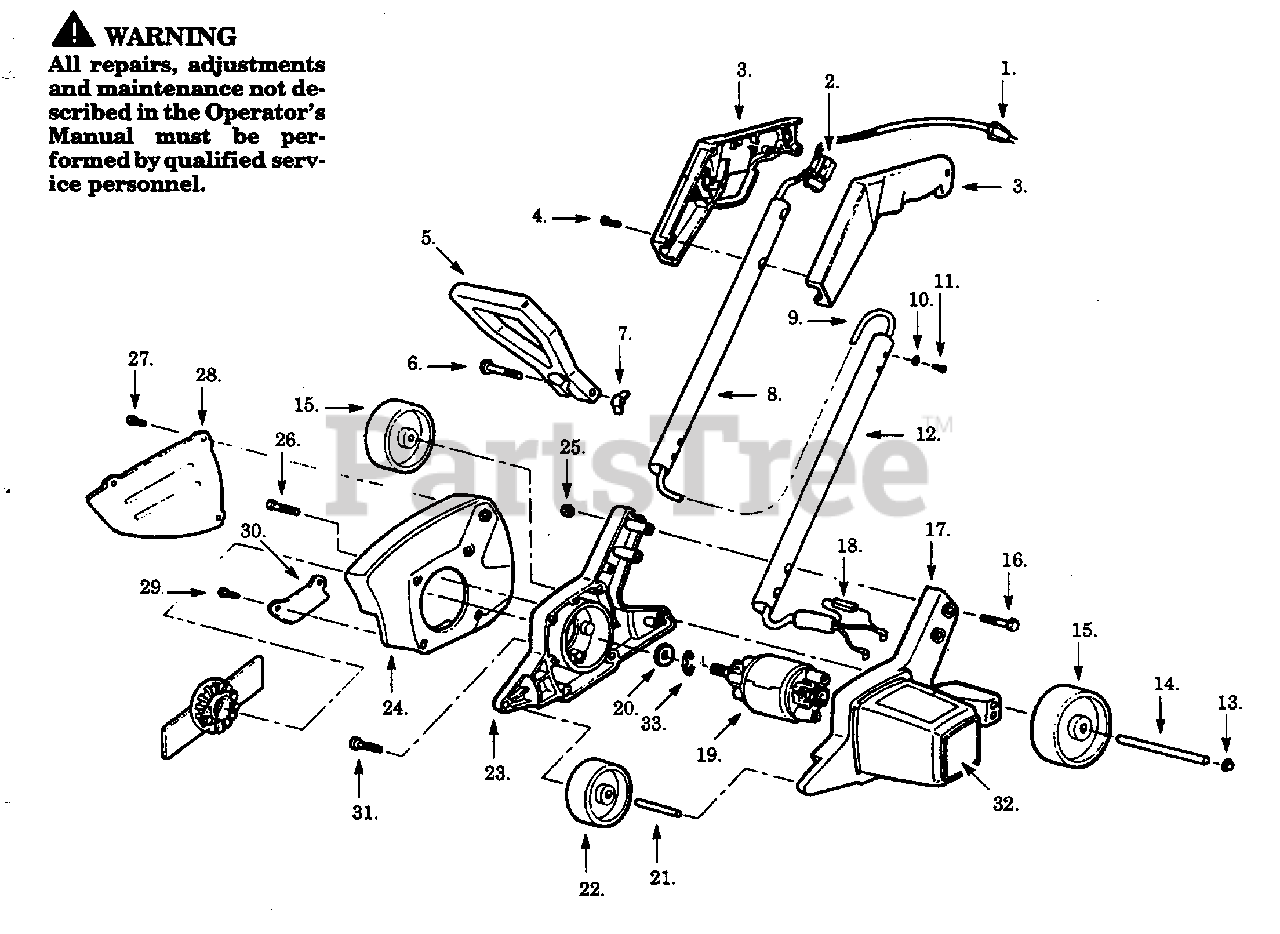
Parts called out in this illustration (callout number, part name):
1	Power Cord
2	Trigger Switch
3	Handle Set
5	Assist Handle
8	Upper Handle Tube
10	Lockwasher
12	Lower Handle Tube
13	Push Nut
17	Motor Cover
18	Rectifier Ass'y.
24	Guard Housing
25	Locknut
28	Side Guard
30	Edge Guide
32	Housing Label
33	Retaining Ring
